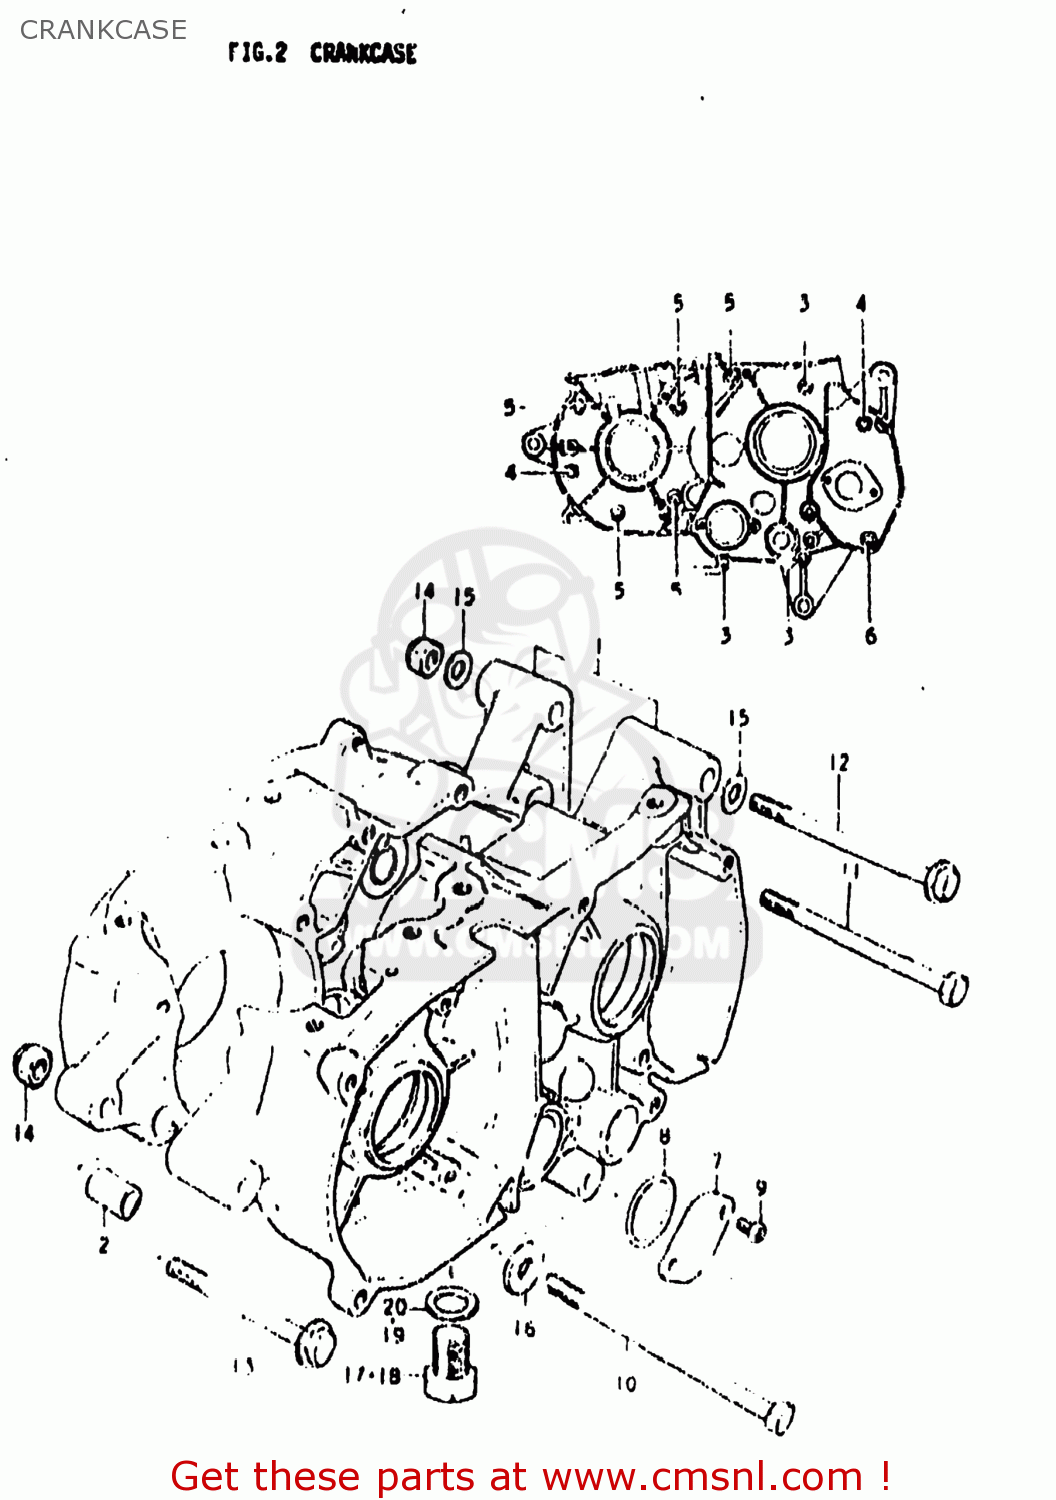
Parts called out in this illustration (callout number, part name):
1	CRANKCASE SET
2	PIN
3	SCREW
4	SCREW (6X45)
5	SCREW (6X35)
6	SCREW
7	CAP,GEAR SHIFT CAM PIVOT
8	O-RING (D:2.4 ID:26.2)
9	SCREW
10	BOLT
11	BOLT 8X100
12	BOLT
13	BOLT 8X75
14	NUT
15	WASHER
16	WASHER
17	PLUG
18	BOLT 10X20
19	GASKET(14X19.2X2) (NAS)
20	GASKET(10X14X3.6) (NAS)
